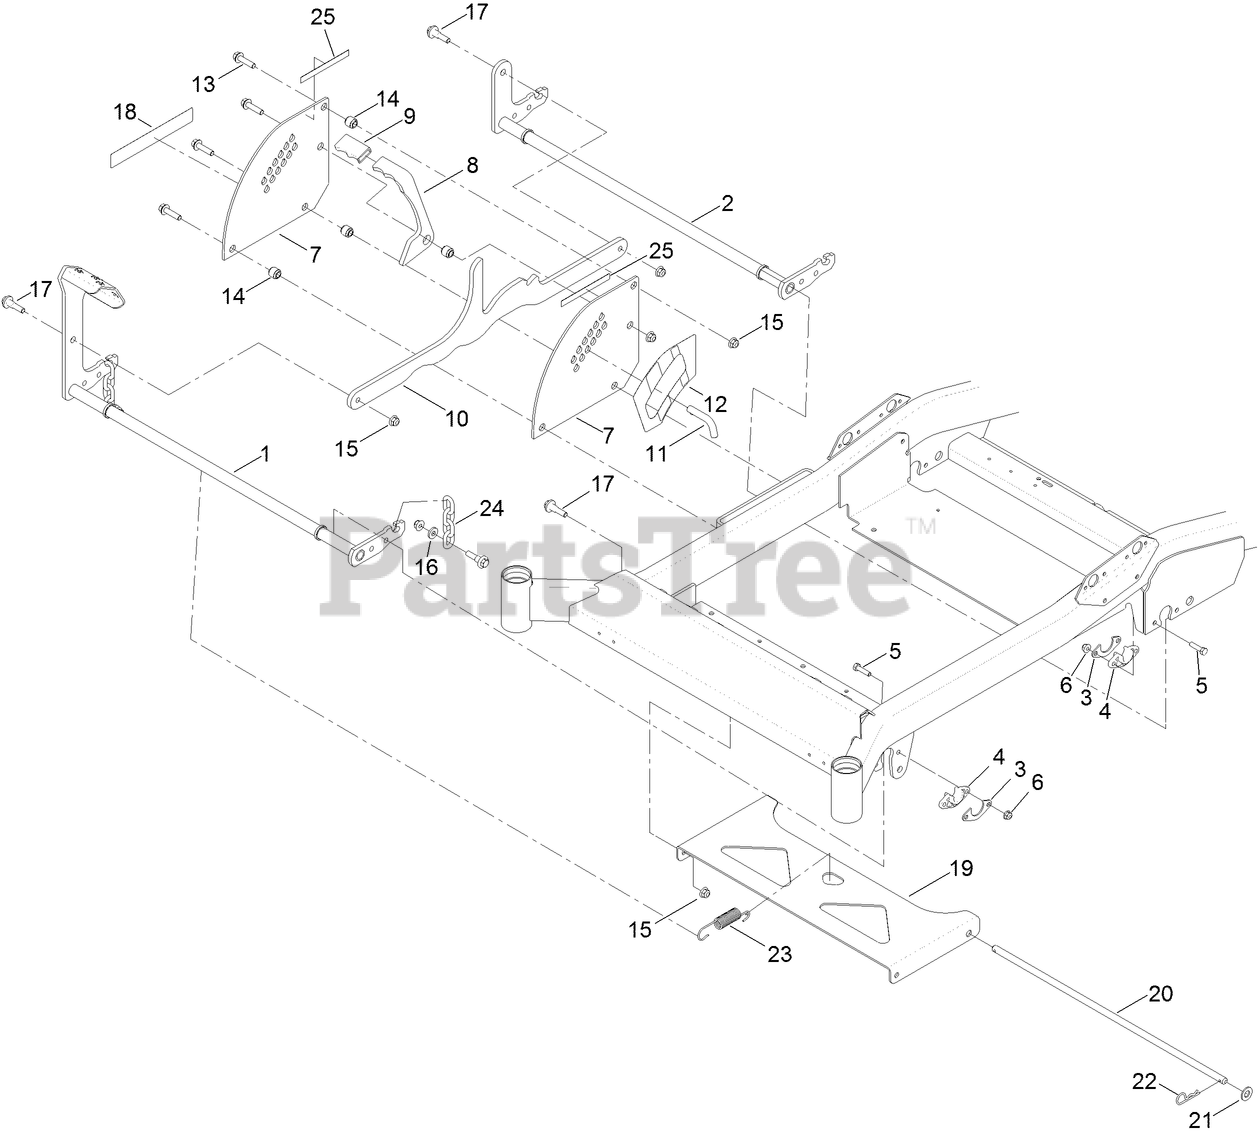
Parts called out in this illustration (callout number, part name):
3	GUSSET-LIFT, DECK
4	BUSHING-FLANGE
5	SCREW-HH
6	NUT-HF, NI
7	PLATE-DECK, LIFT
8	LOCK-TRANSPORT, HOC
9	GRIP-FLAT
10	LINK-HOC
11	PIN-HOC
12	DECAL-HOC
13	SCREW-HHF
14	SPACER-STEP, DOUBLE
15	NUT-HF, NI
16	SPACER
17	BOLT-SHOULDER
19	PAN-DECK, PIVOT
20	ROD-DECK, PIVOT
21	WASHER-FLAT
22	PIN-COTTER
23	SPRING-EXTENSION
24	CHAIN-DECKLIFT
25	PAD-RUBBER
